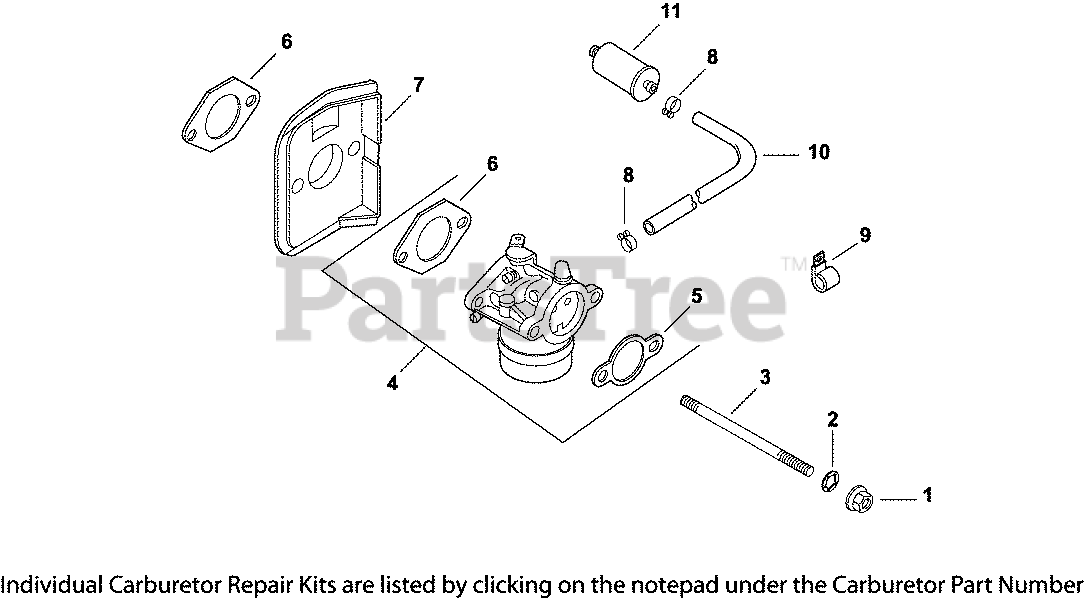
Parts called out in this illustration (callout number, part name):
1	NUT, FLG M6X1.0
2	WASHER, INT TOOTH LOCK 1/4"
3	STUD,M6X1.0X116
4	KIT, CARB W/GASKETS - USE 42 853 03-S
5	GASKET, AIR CLEANER BASE
6	GASKET, CARBURETOR
7	DEFLECTOR, HEAT
8	CLAMP, HOSE (KM)-USE 25 237 31-S
9	CLIP, CABLE
10	LINE, FLEXIBLE FUEL 9.0
11	FILTR,FUEL 75 MICRON (GRAVTY FEED)
